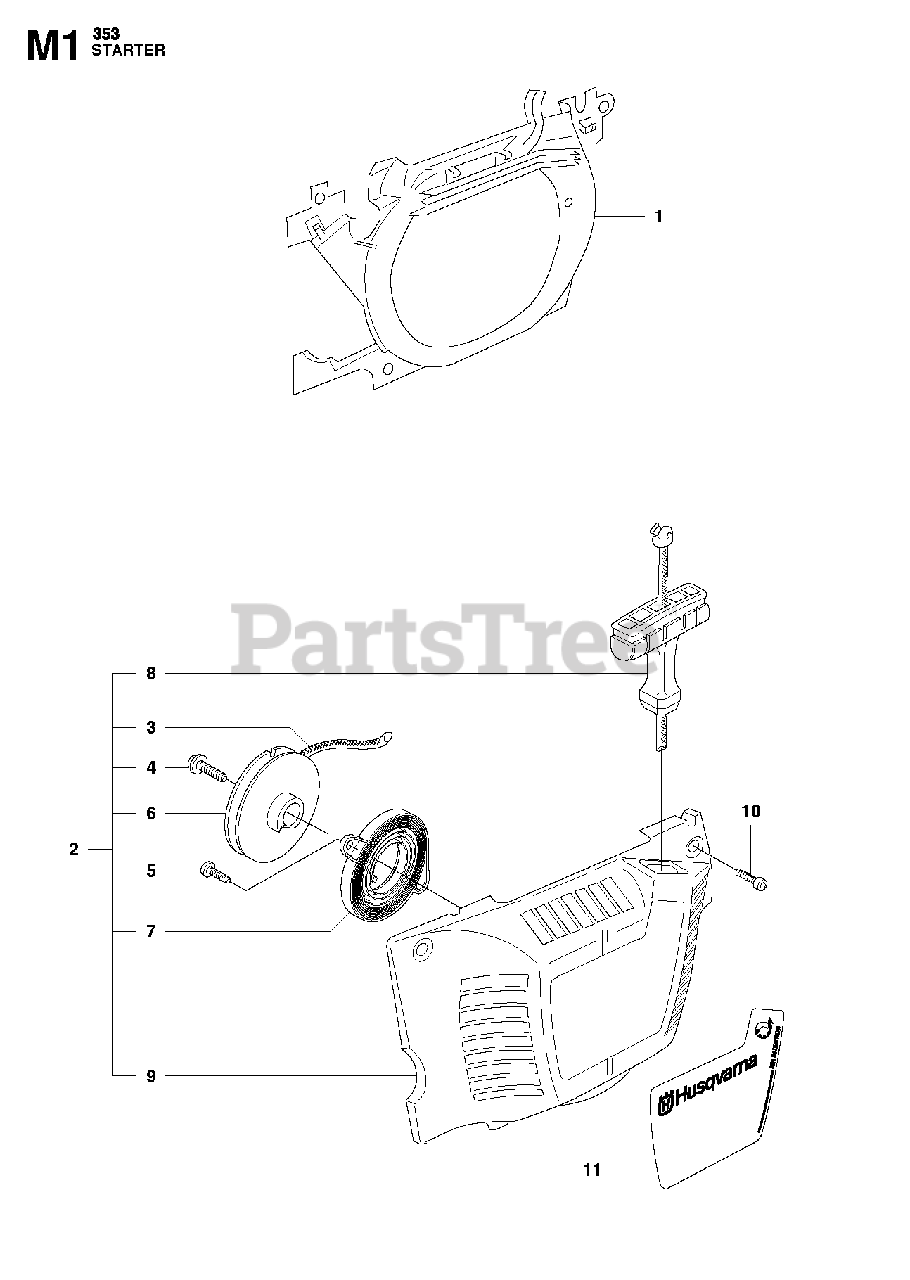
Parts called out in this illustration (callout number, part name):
1	AIR CONDUCTOR
2	STARTER HOUSING ASSY.
3	STARTER ROPE
4	SCREW
5	SCREW
6	PULLEY
7	RETURN SPRING
8	STARTER HANDLE
9	STARTER HOUSING
11	DECAL
11	Decal
